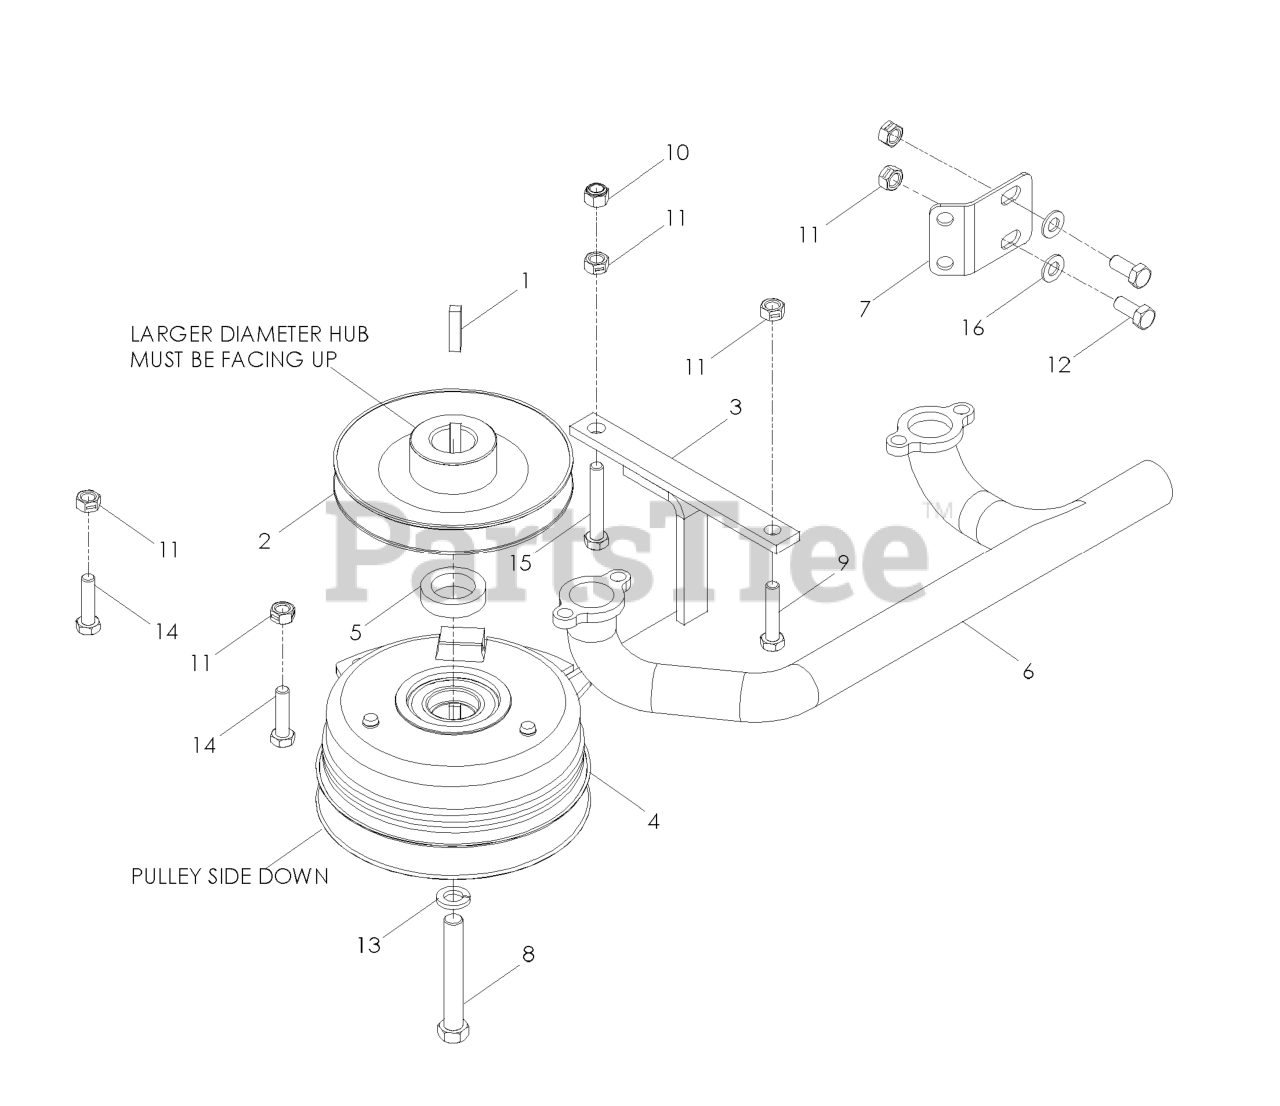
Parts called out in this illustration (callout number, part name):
1	KEY 1/4 SQ X 1 1/8
3	CLUTCH TIE DOWN
4	CLUTCH 125 FT/LB
6	MANIFOLD-EXHAUST, 21HP KAW
7	BRACKET-MUFFLER, BLK
8	HEX SCREW 7/16-20 X 3
9	CAPSCREW 5/16 X 1/1/2 HEX HEAD
10	NUT 5/16 NYLOC
11	NUT 5/16C CENTERLOCK
12	SCREW 5/16C X 1 HEX CAP
13	WASHER 7/16 LOCK
14	HCS 5/16C X 1 1/4
15	HCS 5/16-18X2
16	FLAT WASHER 5/16 SAE
